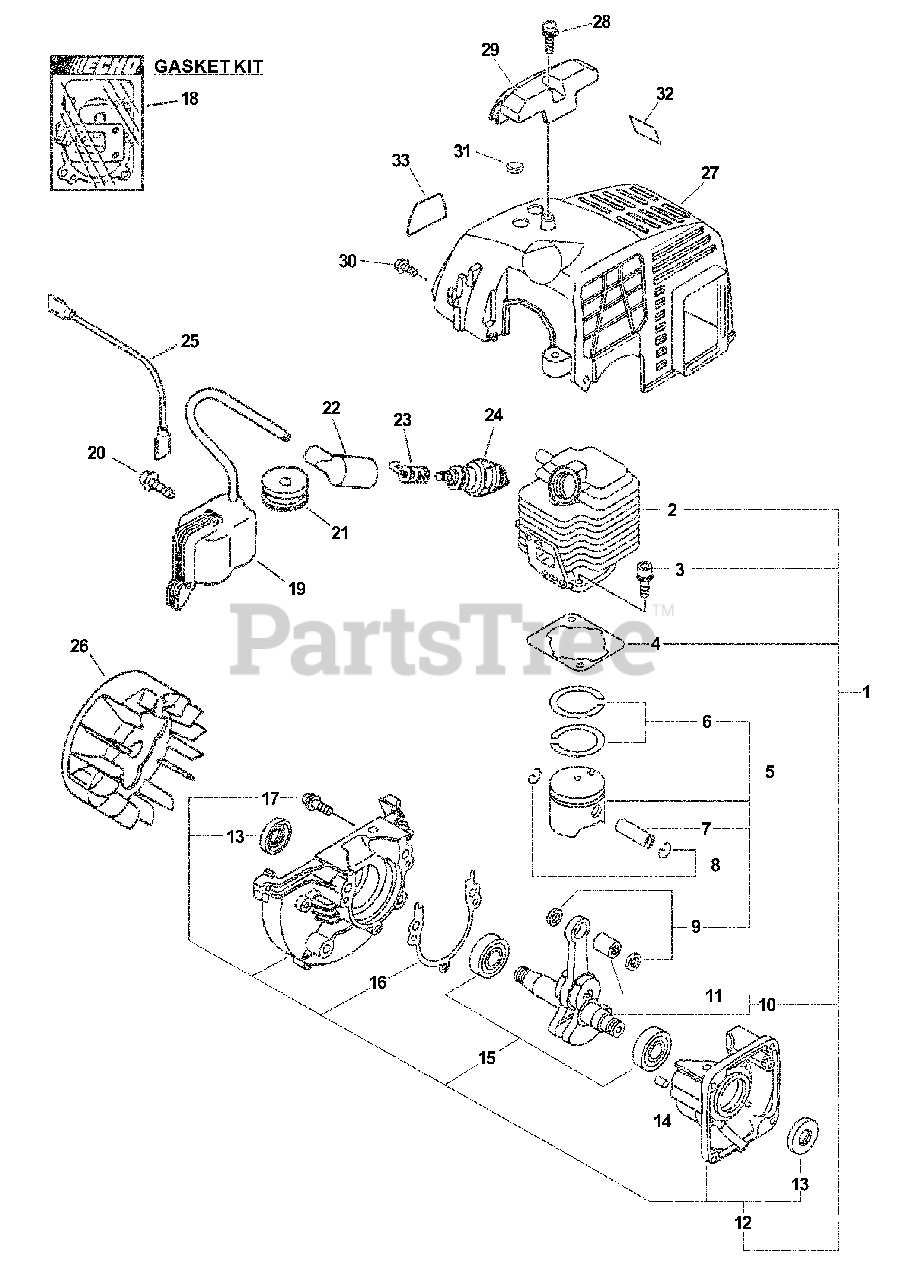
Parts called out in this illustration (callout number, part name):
1	SHORT BLOCK -- SB1048
2	CYLINDER
3	SCREW - 5X22
4	GASKET, CYLINDER
5	PISTON KIT
6	RING, PISTON
7	PIN, PISTON
8	RING, RETAINING
9	SPACER, PISTON
10	CRANKSHAFT ASSY
11	BEARING, NEEDLE - 8
12	CRANKCASE KIT
13	SEAL, OIL
14	PIN - LOCATING
15	BEARING, BALL - 6201
16	GASKET, CRANKCASE
17	SCREW - 5X28
18	GASKET KIT
19	COIL, IGNITION
20	SCREW - 4X22
21	GROMMET
22	CAP, SPARK PLUG
23	TERMINAL, SPARK PLUG CAP
24	SPARK PLUG -- BPM-7A
25	LEAD - IGNITION
26	FLYWHEEL
27	COVER, ENGINE
28	SCREW - 5X16 -- TAPPING
29	GUARD, TOP - GRAY
30	SCREW - 4X12 -- TAPPING
32	LABEL - HOT SURFACE
33	LABEL - MODEL PE-201
